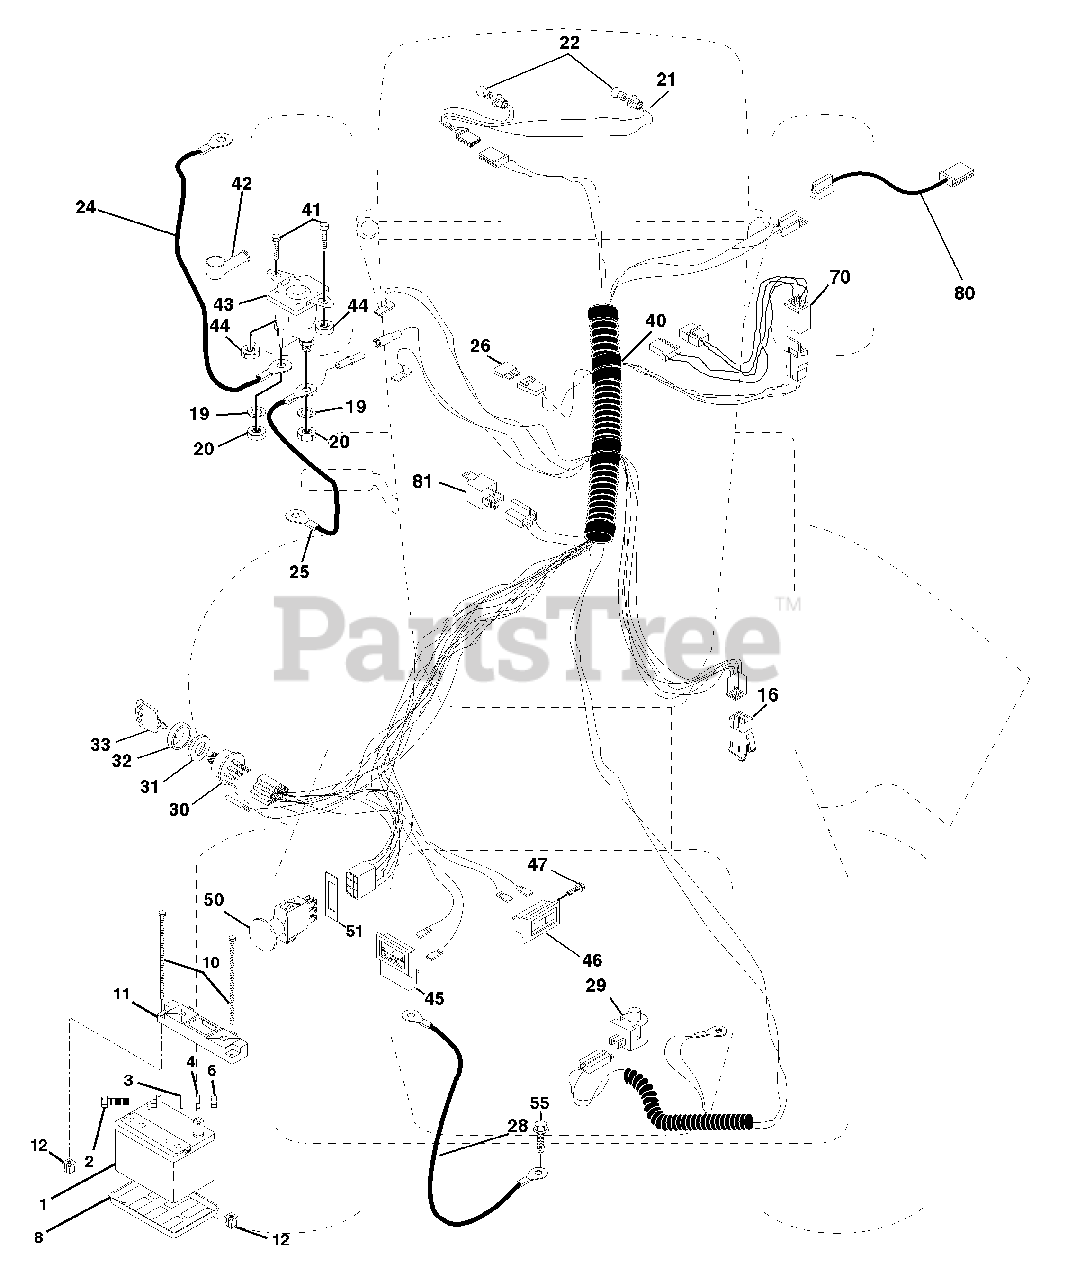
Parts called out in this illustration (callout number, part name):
1	Battery 12 Volt 30 AMP Wet
2	Bolt Hex Hd 1/4-20unc X 3/4
3	Washer 9/32 X 5/8 X 16 Ga.
4	Washer Lock Hvy Helical 1/4
6	Nut Fin Hex 1/4-20 Unc
8	Tray, Battery 7.80 x 5.25 Blk
10	Bolt BTR FRT 1/4-20 x 7.5 zinc
11	Holddown Battery, Front mount
12	Nut, Push Nylon 1/4 battery FRT
16	Switch Interlock Push-In
19	Washer Lock 1/4
20	Nut Jam Hex 1/4-20 Unc
21	Harness Asm Light W/4152j
22	Bulb Light #1156
24	Cable Starter 6 Ga 11" Red
25	Cable Battery 6 Ga 22" w/16W
26	Fuse 30 AMP Auto Green
28	Cable Ground 6 Ga 21" black
29	Switch Plunger Normal Op Olive
30	Switch Ign 4 pos w/lights
31	Nut Ignition
32	Cover Sw Ignition
33	Key Ign Molded
40	Harness Ign. Stl Elec CI Am Hm
41	Bolt Blk Fin Hex 1/4 - 20 x 1/2
42	Cover Terminal Red
43	Solenoid
44	Nut Keps Hex 1/4-20 Unc
45	Ammeter, retangular 6 amp
46	Meter, Hour
47	Screw 10-24 x 1/2 Black
50	Switch PTO 3 PTD Black
51	Ring Retainer PTO
55	Screw THDROL 5/16-18 x 1/2 TYT
70	Harness, Eng.
80	Harness, Clutch EVX
